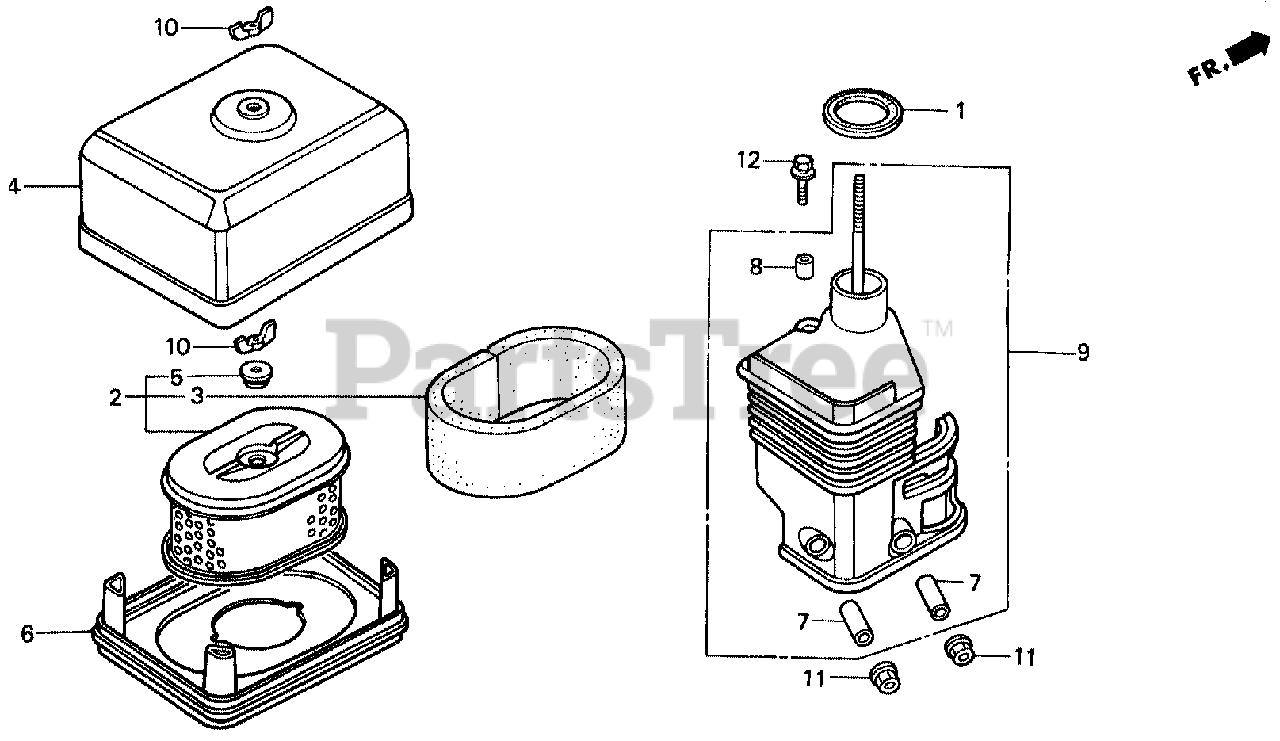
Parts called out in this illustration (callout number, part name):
1	GASKET, ELBOW
2	ELEMENT, AIR CLEANER (DUAL)
3	FILTER (OUTER)
4	COVER, AIR CLEANER (DUAL)
5	GROMMET, AIR CLEANER
6	NOSE, MUFFLER
7	COLLAR, AIR CLEANER
8	COLLAR B, AIR CLEANER
9	ELBOW, AIR CLEANER
10	WINGNUT, TOOL BOX SETTING
11	NUT, FLANGE (6MM)
12	BOLT, FLANGE (6X20)
